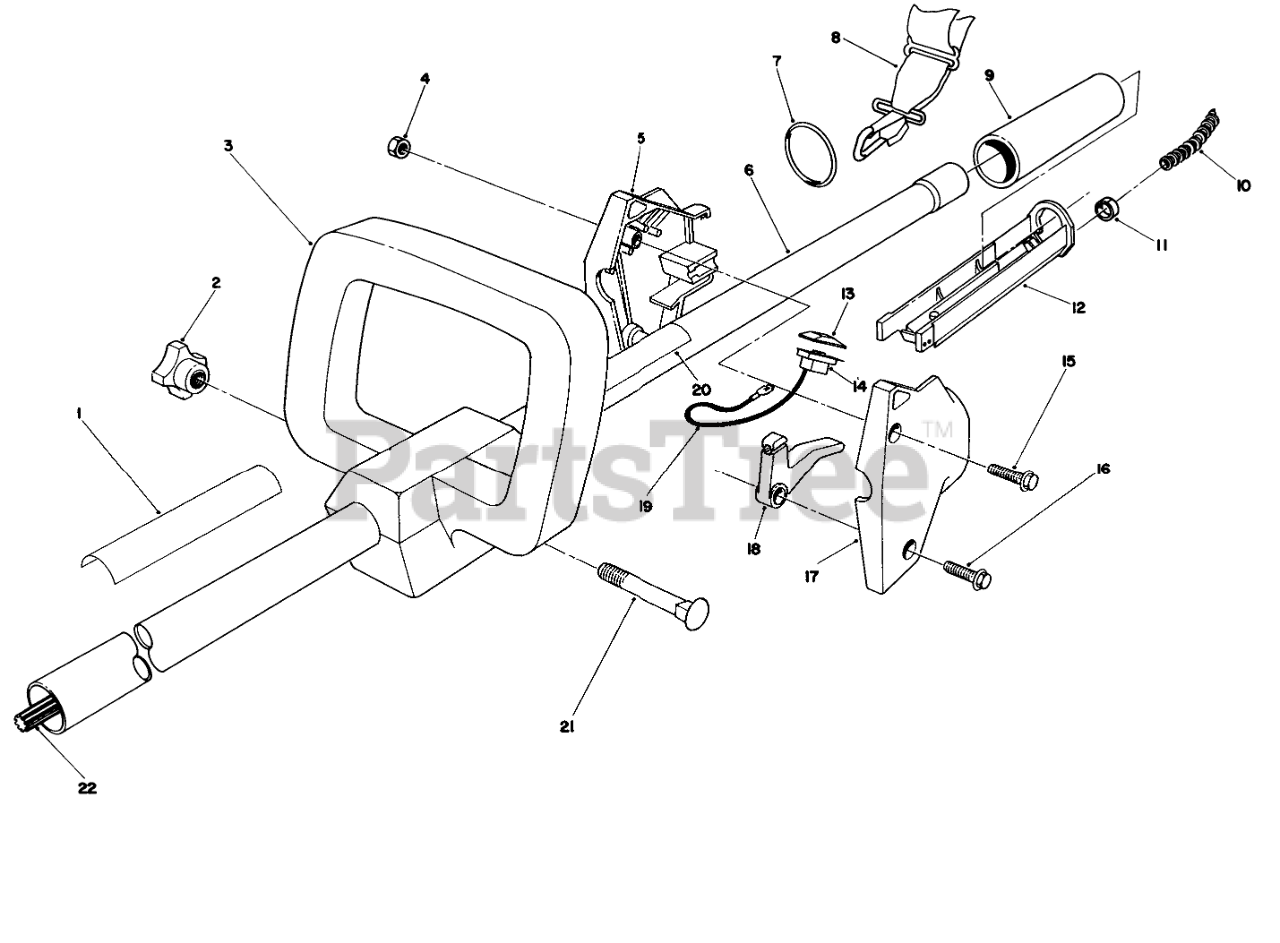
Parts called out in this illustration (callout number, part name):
1	Decal Model No.
2	Knob
3	HANDLE SECONDARY
4	NUT-LOCK, NI
5	THROTTLE HSG.R H
6	TUBE ASSEMBLY
7	RING-HARNESS
8	Harness
9	GRIP - RUBBER
10	CABLE COVER
11	RING FITTING
12	TROUGH 1"
13	SWITCH COVER-BLACK
14	SWITCH
16	SCREW-HWH
17	THROTTLE HSG. L H
18	THROTTLE LEVER
19	WIRE ASM
20	Decal
21	BOLT-CARRIAGE
22	SPLINED SHAFT
